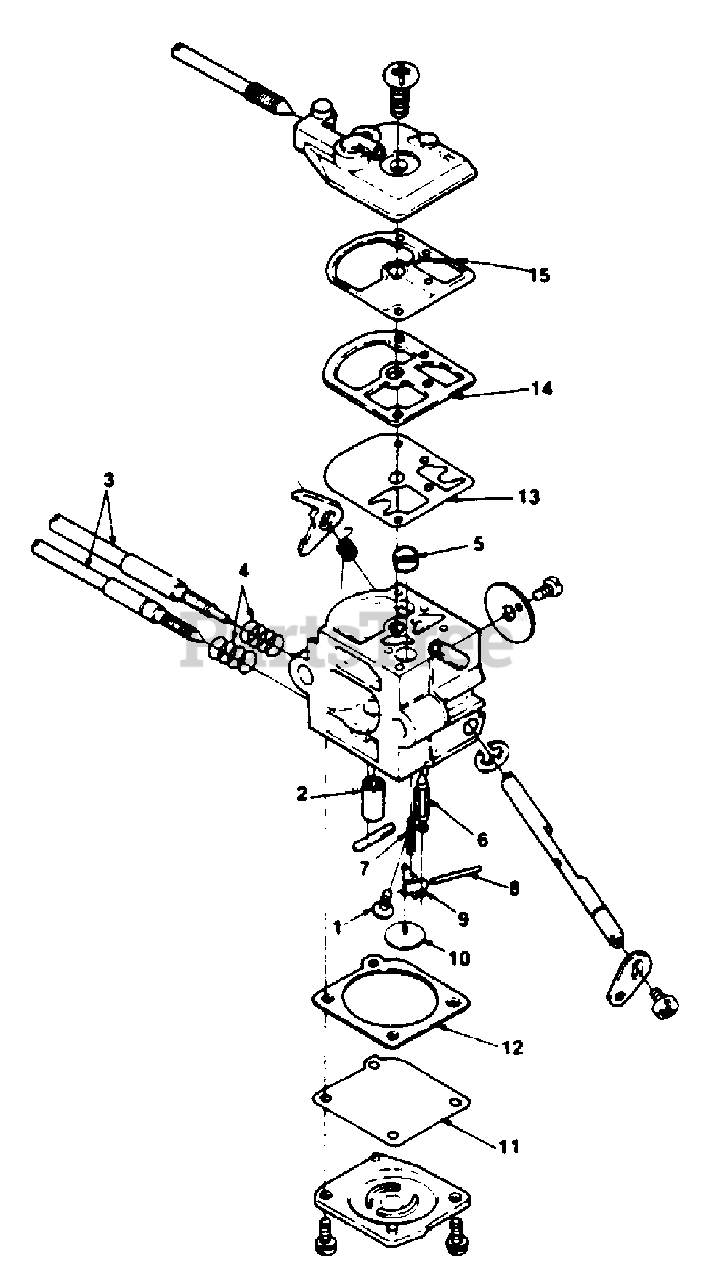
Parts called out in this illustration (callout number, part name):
1	Repair Kit
2	Repair Kit
3	Repair Kit
4	Repair Kit
5	Repair Kit
6	Repair Kit
7	Repair Kit
8	Repair Kit
9	Repair Kit
10	Repair Kit
11	Repair Kit
12	Repair Kit
13	Repair Kit
14	Repair Kit
15	Repair Kit
